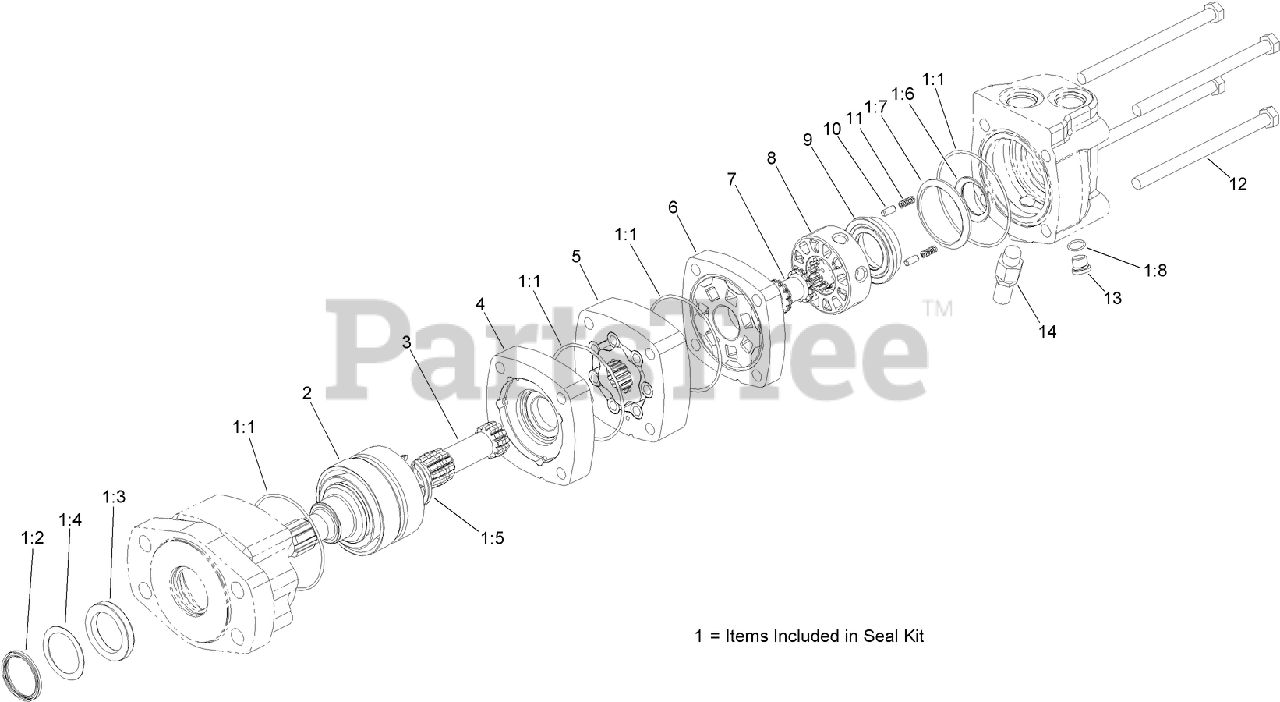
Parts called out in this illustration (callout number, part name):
1	SEAL KIT
1:1	SEAL
1:2	EXCLUSION SEAL
1:3	Outer Face Seal
1:4	Inner Face Seal
1:5	Shaft Face Seal
1:6	SHAFT SEAL
1:7	Back-Up Washer
1:8	O-RING
2	SHAFT SUB ASM
4	Plate-Wear
5	GEROLER SUB ASM
6	Plate-Valve
7	DRIVE-VALVE
8	Valve
9	Plate-Balancing
11	SPRING
13	PLUG ASM
14	SENSOR-SPEED
